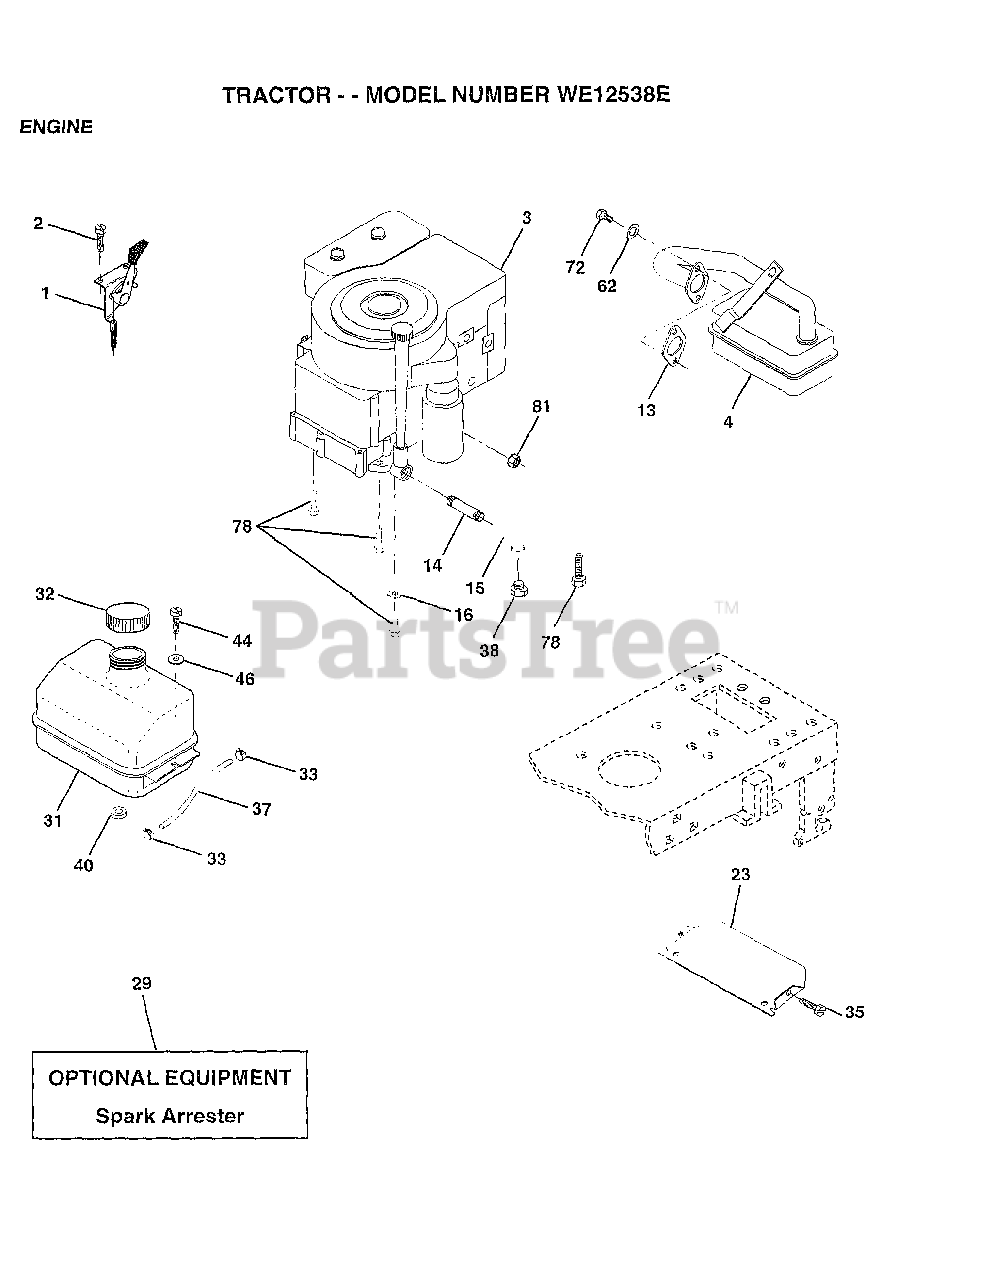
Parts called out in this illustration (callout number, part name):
1	CONTROL THROTTLE
2	SCREW LT
4	MUFFLER
13	GASKET ENG 1 313 LD TIN PLATED
14	PIPE NIPPLE
15	ELBOW
16	LOCKWASHER
23	SHIELD-HEAT
31	TANK.FUEL.LT.
32	CAP ASM FUEL
33	HOSE CLAMP
35	SCREW
37	LINE FUEL
44	SCREW HEX CRT
46	WASHER
62	LOCKWASHER
72	SCREW
78	SCREW
81	NUT
